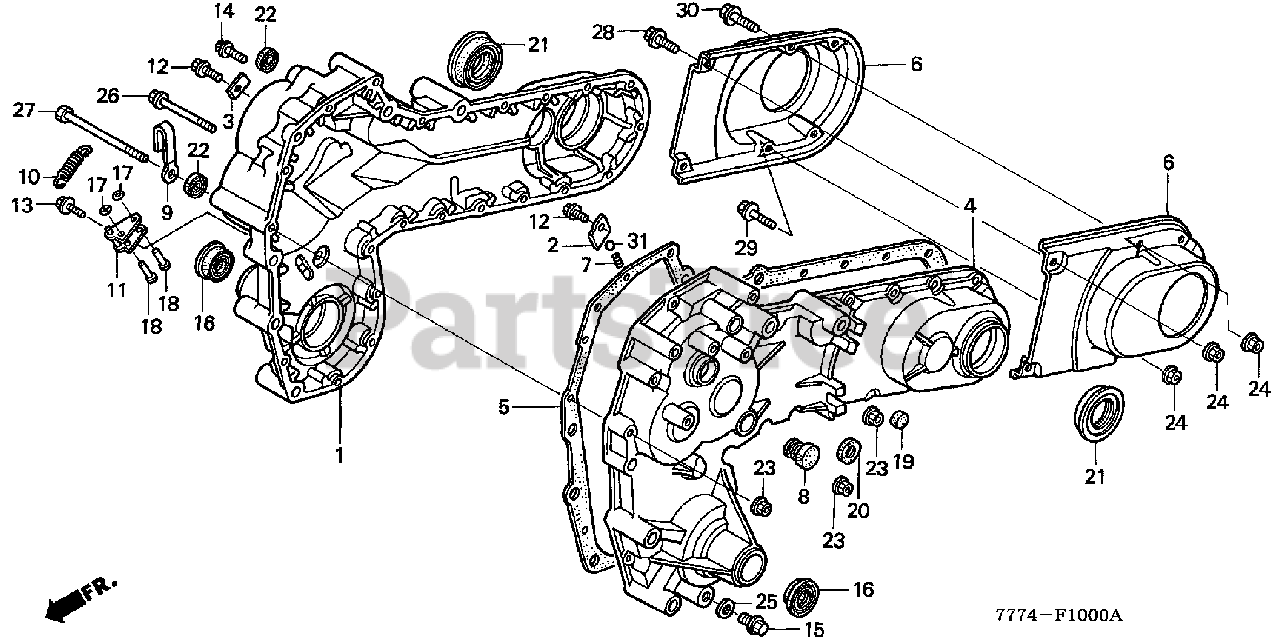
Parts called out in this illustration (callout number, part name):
1	CASE, R. TRANSMISSION
2	PLATE, BALL STOPPER
3	PLATE, CABLE STOPPER
4	CASE, L. TRANSMISSION
5	GASKET, TRANSMISSION CASE
6	PROTECTOR, CASE
7	SPRING, BALL SETTING
8	CAP, OIL HOLE
9	CLIP, SUB-WIRE
10	SPRING, DIFFERENTIAL LOCK LEVER
11	ARM, DIFFERENTIAL LOCK
12	BOLT, FLANGE (6X14) (CT200)
13	BOLT, FLANGE (6X18)
14	BOLT, FLANGE (6X25)
15	BOLT, DRAIN PLUG (12X15)
15	BOLT, DRAIN PLUG
16	OIL SEAL (20X36X8)
17	WASHER, SPECIAL (5MM)
18	PIN, CHANGE (5X23)
19	PLUG, SEALING (16) (ARAI)
20	OIL SEAL (15X24X5)
21	OIL SEAL (40X55X7)
22	OIL SEAL (12X22X6)
23	NUT, FLANGE (6MM)
24	NUT, FLANGE (8MM)
25	WASHER, DRAIN PLUG (12MM)
26	BOLT, FLANGE (6X80)
27	BOLT, FLANGE (6X120)
28	BOLT, FLANGE (8X35)
29	BOLT, FLANGE (8X40)
30	BOLT, FLANGE (8X45) (DENSO)
31	BALL, STEEL (#8) (1/4)
